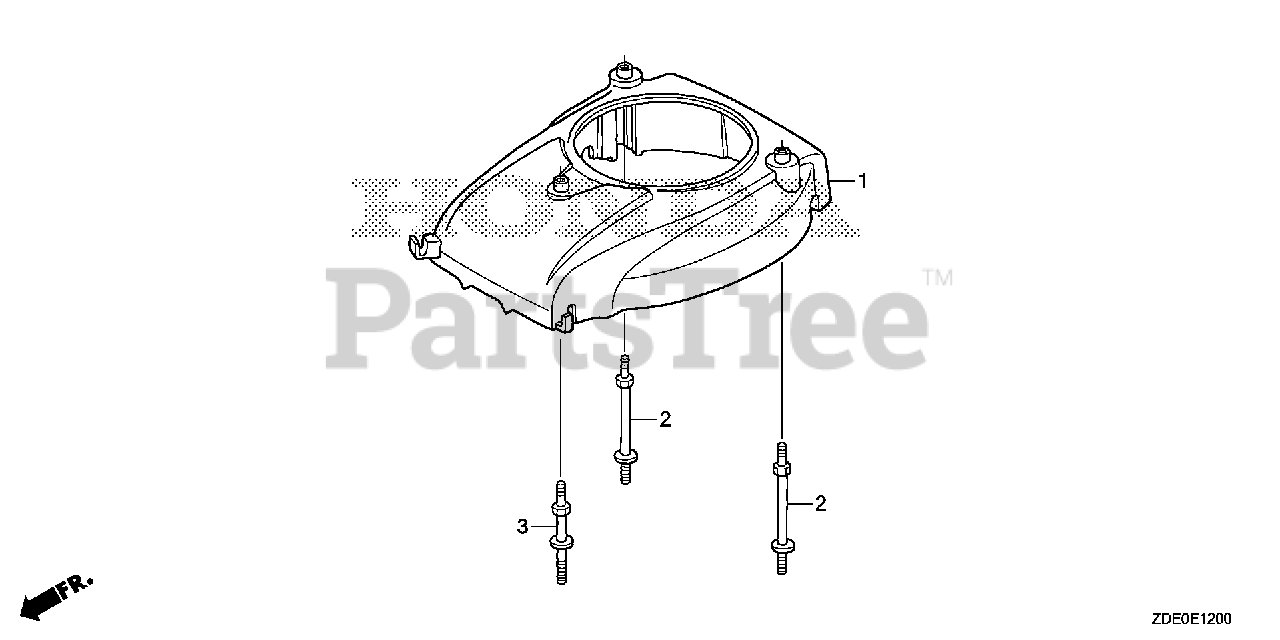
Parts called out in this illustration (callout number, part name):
1	COVER, FAN *R280* (POWER RED)
2	BOLT A, STUD
3	BOLT B, STUD
